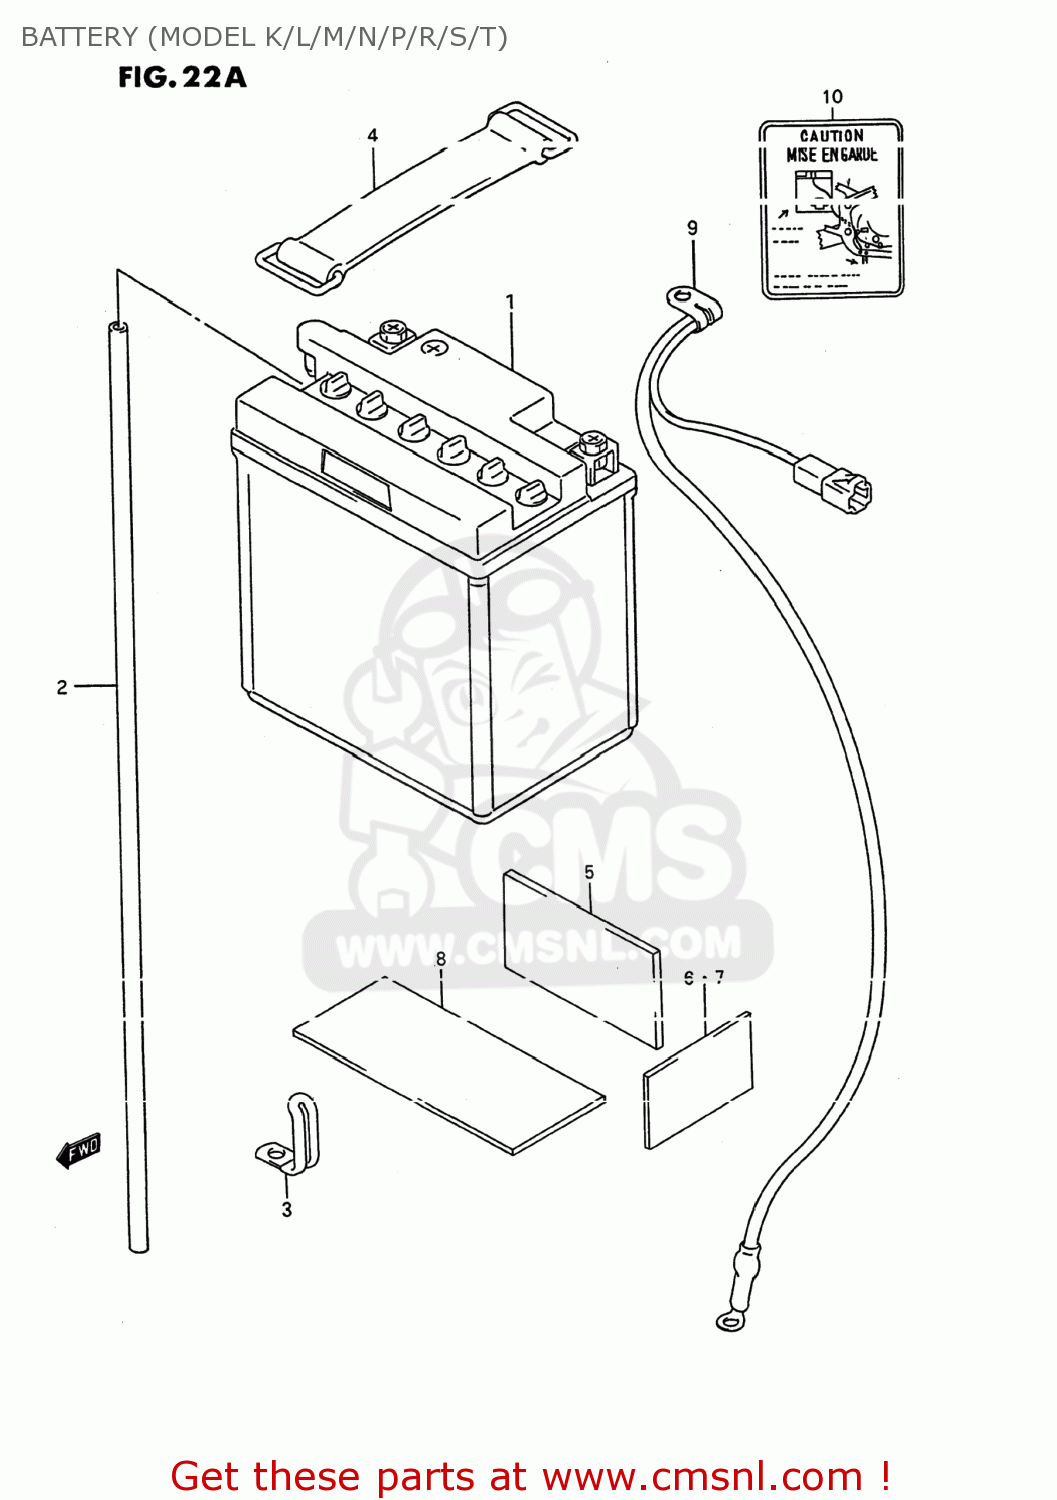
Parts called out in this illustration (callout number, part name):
1	BATTERY(YB10L-B2,12V11.6AH)
2	HOSE,BATTERY EXHAUST
3	CLAMP(L:35)
4	BAND
5	PROTECTOR,20X9
6	PROTECTOR(50X50X5)
7	PROTECTOR(170X95X3.0)
8	PROTECTOR(170X95X3.0)
9	WIRE,BATTERY MINUS LEAD
10	PLATE,BATTERY CAUTION
